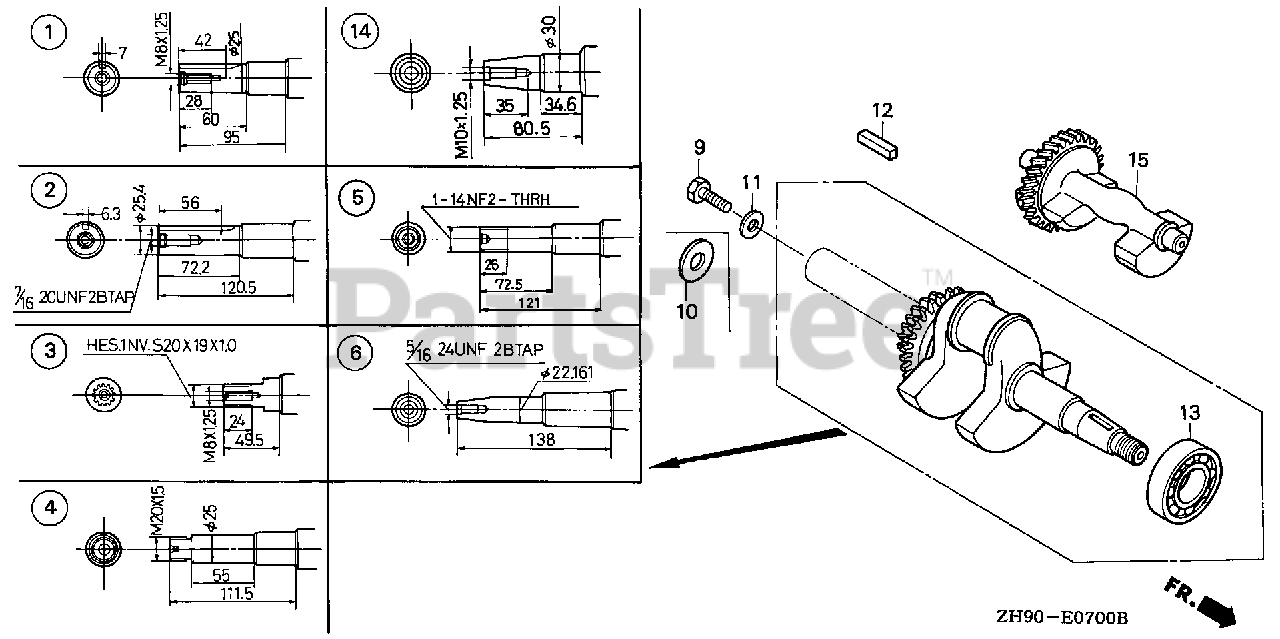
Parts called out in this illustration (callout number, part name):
6	CRANKSHAFT
13	BEARING, RADIAL BALL (6206 SH)
15	WEIGHT, BALANCER
